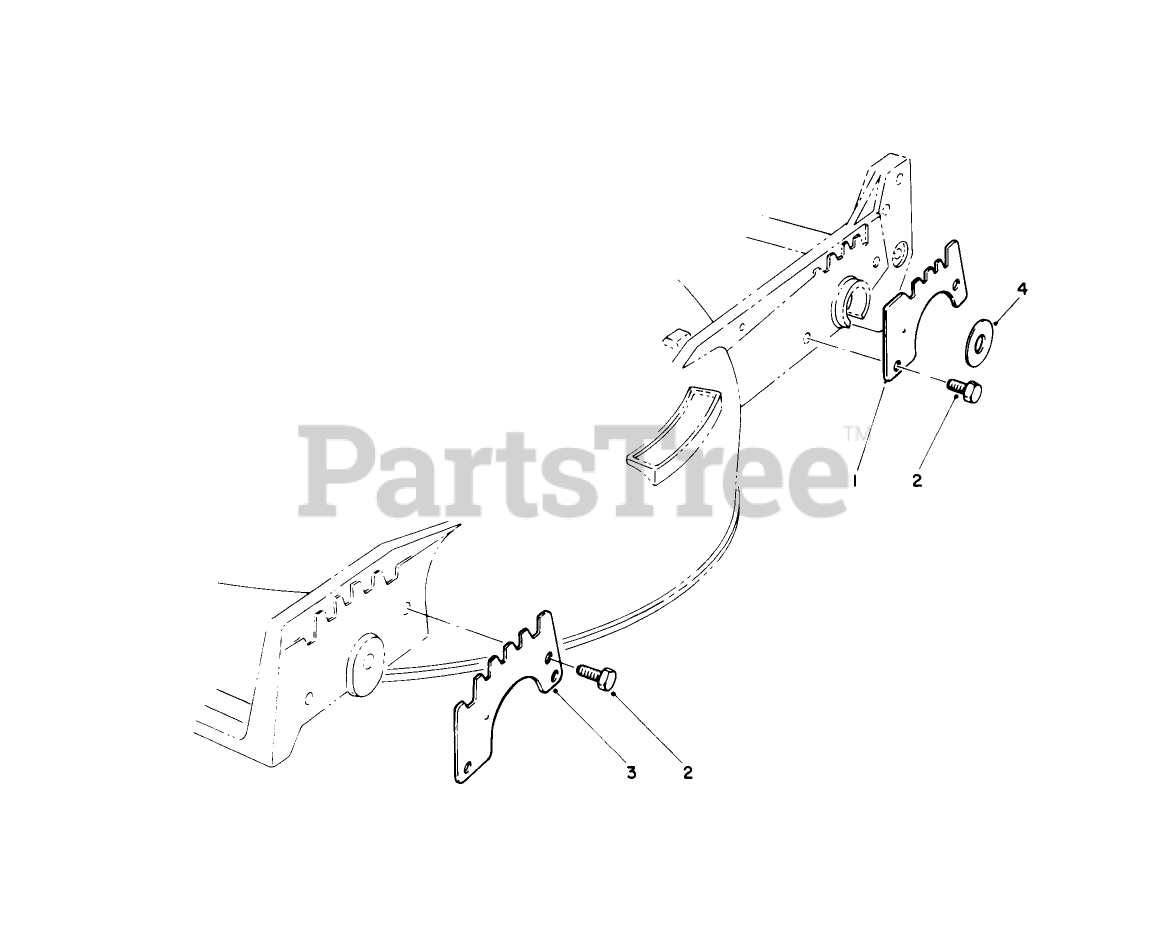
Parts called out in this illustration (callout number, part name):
1	WEAR PLATE,REAR
2	SCREW-HWH
3	WEAR PLATE
4	PIVOT WASHER
